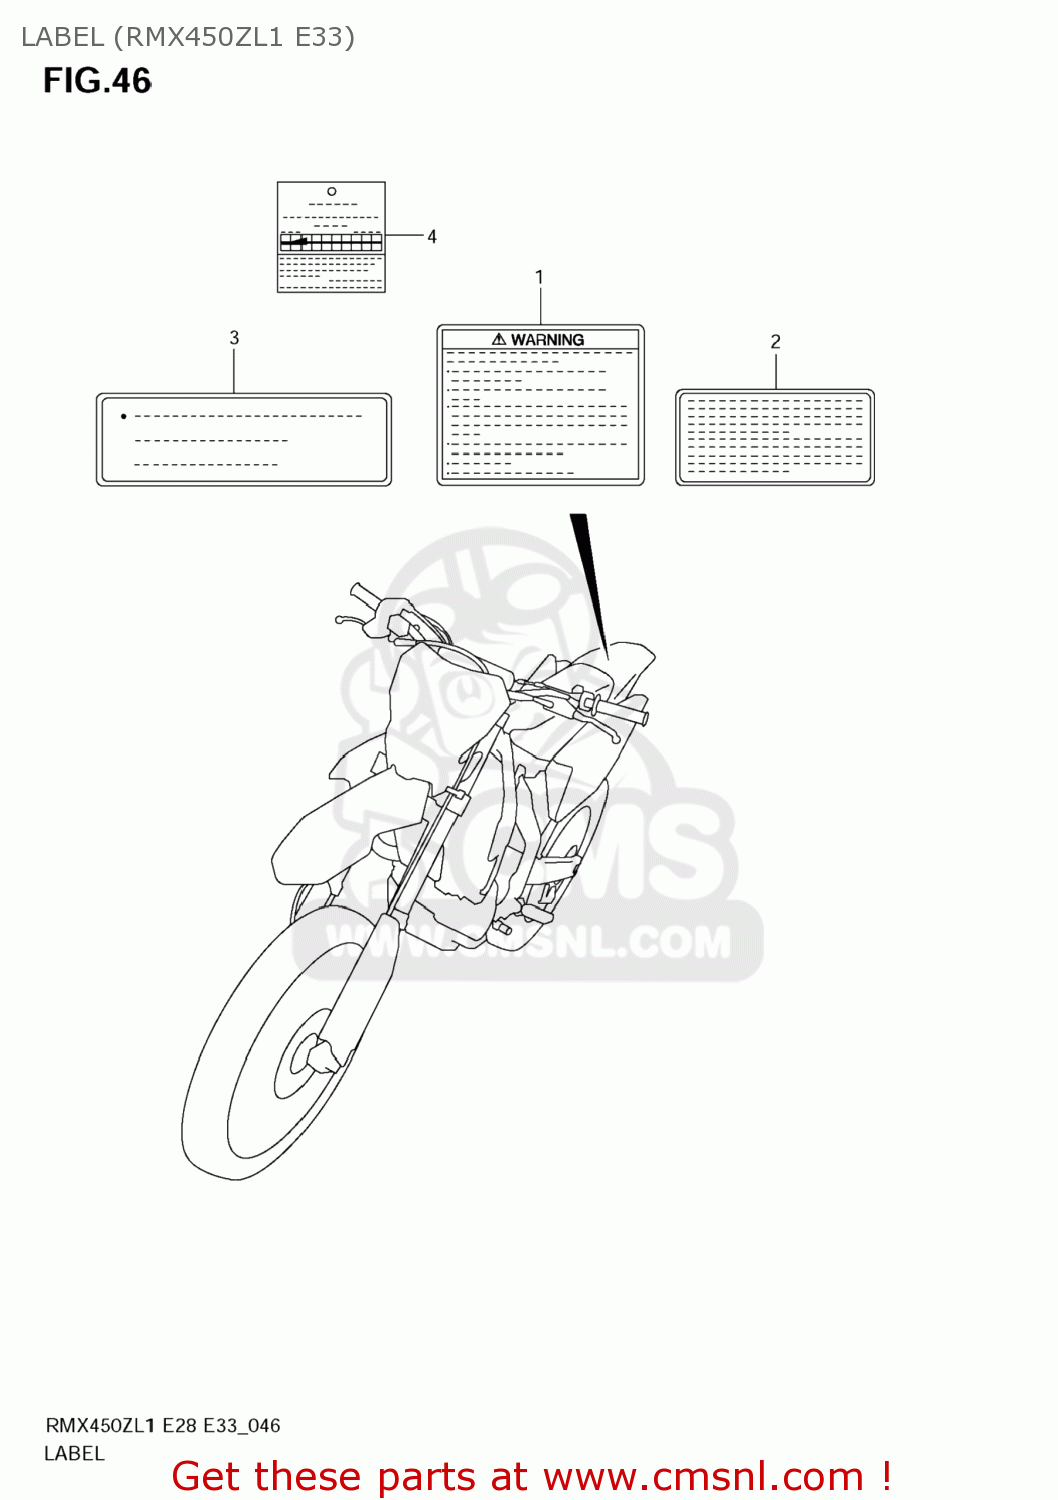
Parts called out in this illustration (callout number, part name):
1	LABEL,GENERAL WARNING
2	LABEL,MANUAL NOTICE
3	LABEL,FUEL INFORMATION
4	TAG,CONSUMER INFORMATION
5	MANUAL,OWNER'S
